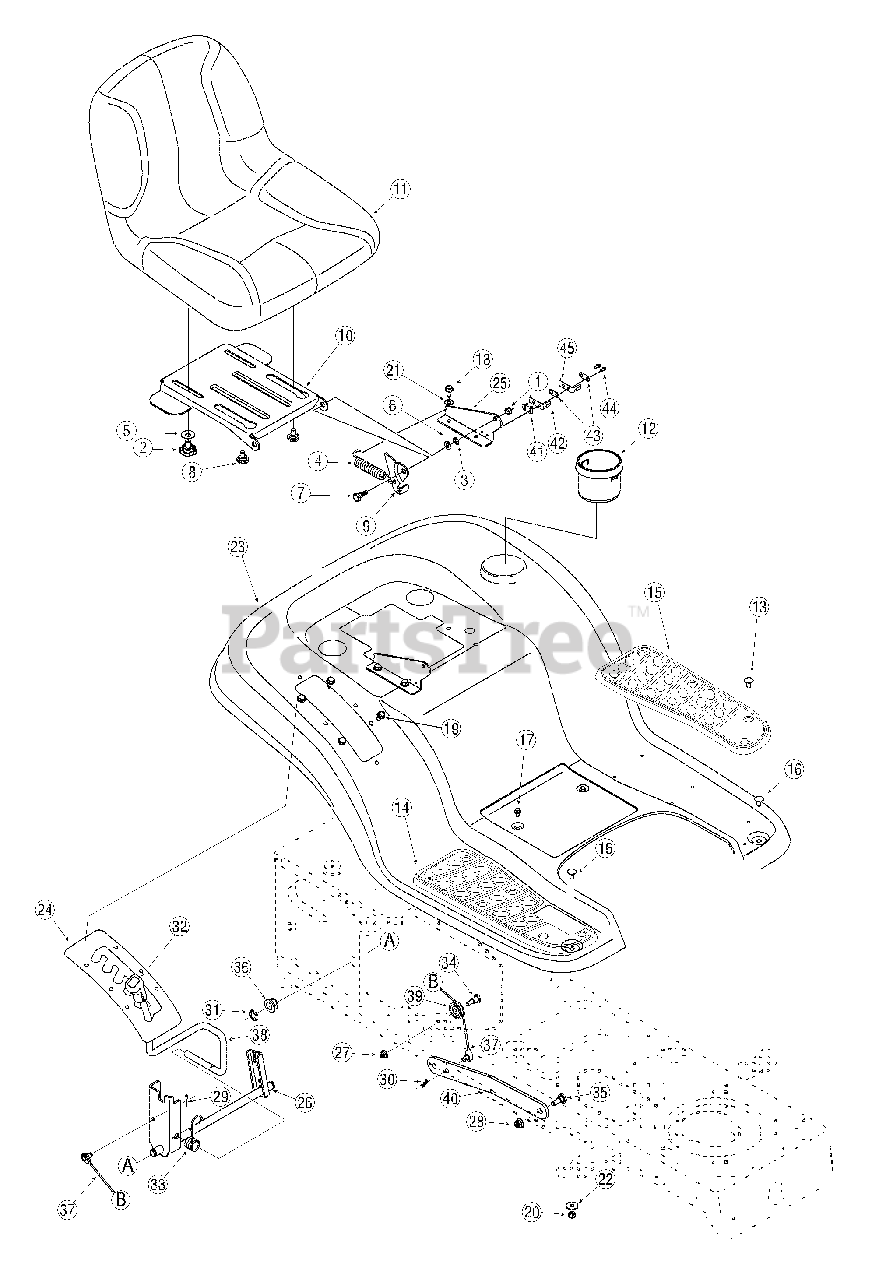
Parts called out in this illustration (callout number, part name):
1	Flange Lock Nut, 5/16-18
2	Knob 3/8-16 x .625
3	Speed Clip
4	Extension Spring,.84 x 4.6
5	Flat Washer, .406 x 1.00 .030
6	Flat Washer, .344 x .688 x .065
7	Shoulder Screw,.437 x.286
8	Shoulder Screw .625 x .175: 3/8-16
9	Seat Lift Bracket
11	High Back Seat Black
12	Cup Holder
13	Ratchet Clips
14	Foot Pad - RH
15	Foot Pad - LH
16	Carriage Bolt, 5/16 x.62
17	Self-tapping Screw, 1/4-20 x.50
18	Self-tapping Screw, 5/16-18 x.625
19	Self-tapping Screw, 5/16-18 x.75
20	Flange Lock Nut, 5/16-18
21	Lock Washer 5/16
22	Flat Washer,.349 x 1.0 x.063
27	Flange Lock Nut, 5/16-18
28	Flange Lock Nut, 3/8-16
29	Hairpin Clip
30	Cotter Pin
31	E-Ring
32	Handle Grip
33	Torsion Spring
34	Hex Cap Screw, 5/16-18 x.62
35	Shoulder Screw, 3/8-16
36	Hex Flange Bearing
37	Lift Cable, 16.16
38	Lift Handle
39	Roller Pulley
41	Plate, Insulator Boss
42	Spring Switch, Outer
43	Plate, Insulator
44	Spring Switch, Inner
45	Screw, #8-18 x .50
